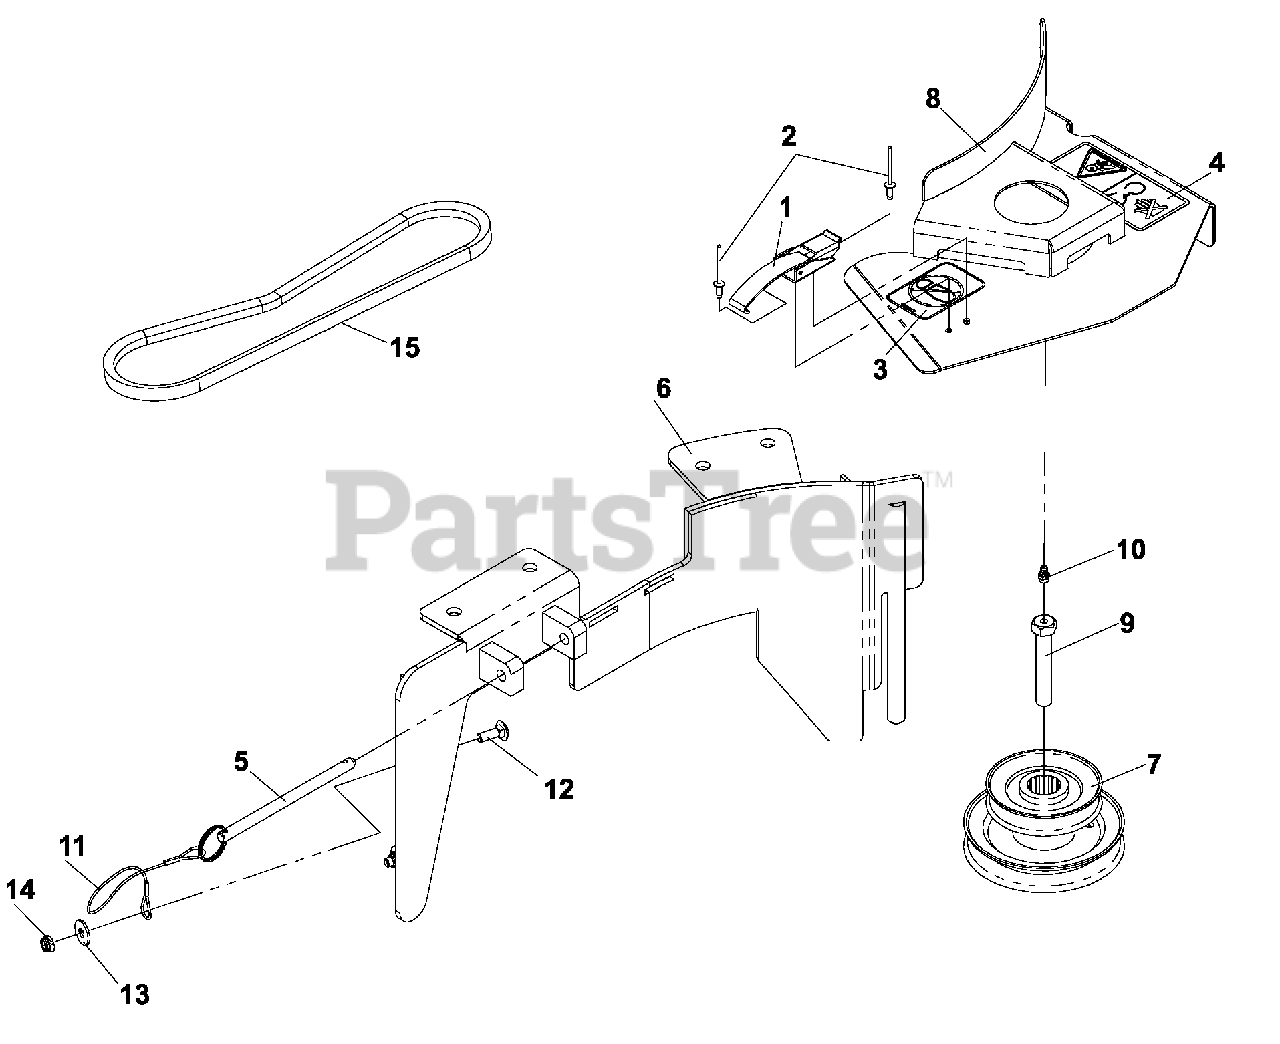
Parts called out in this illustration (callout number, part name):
1	DRAW LATCH
2	RIVET, BLIND, DOME STYLE, 5/32 DIA.
3	DECAL, NO STEP
4	DECAL, DANGER BELT DRIVES
6	BLOWER DECK PLATE, 42/48
7	PULLEY, STACKED DOUBLE, 42/48
8	BELT SHIELD W/DECALS & LATCH, 42"
9	HCS, 7/16-20 X 2 1/2, GR5, SPEC.
10	ZERK
12	RHSNB, 1/4-20 X 3/4, GR2
13	WASHER, 1/4
14	NUT, 1/4C, THIN NYLOC
